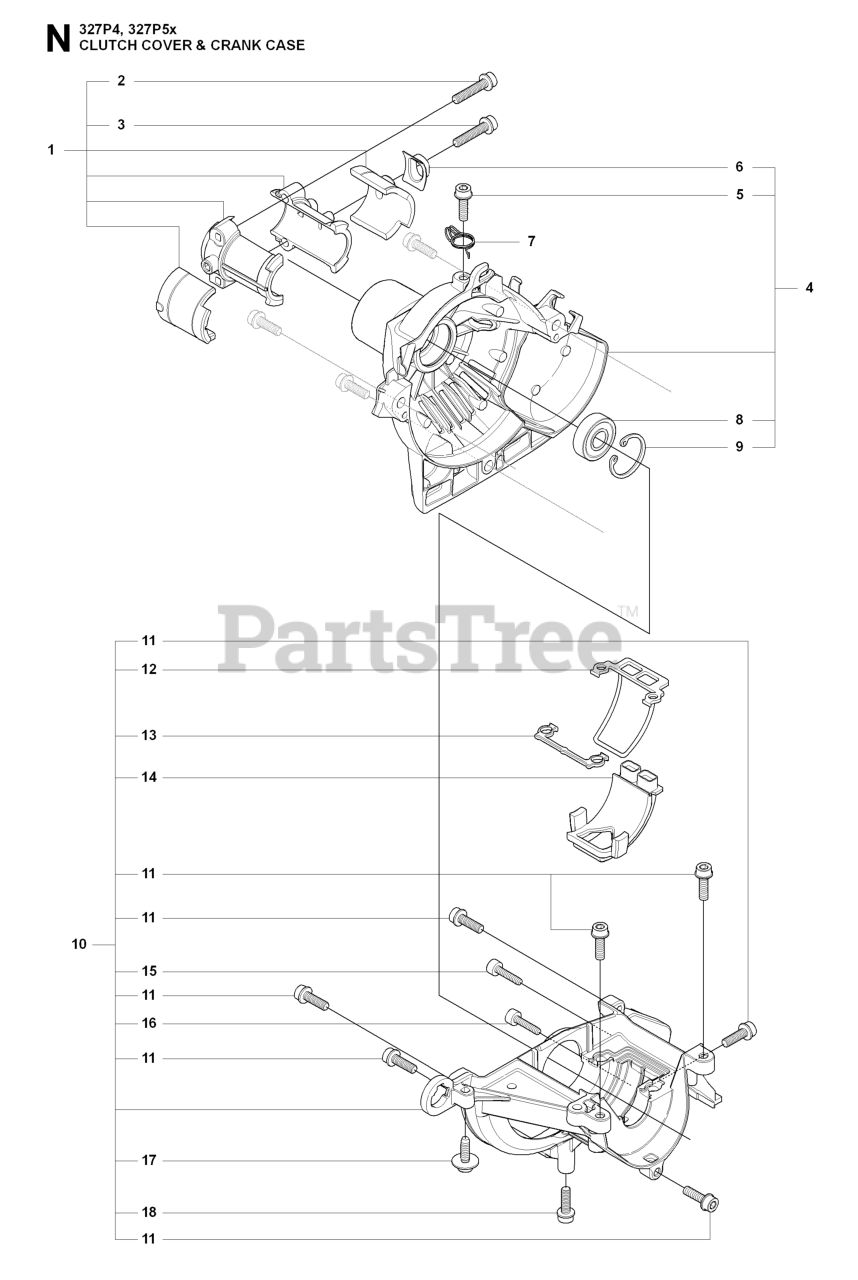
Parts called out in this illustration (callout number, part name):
1	COMPRESION SLEEVE/ISOLATOR SET
4	CLUTCH COVER
5	SCREW
6	PROTECTION PLATE
9	RETAINING RING
10	CRANKCASE
18	SCREW
